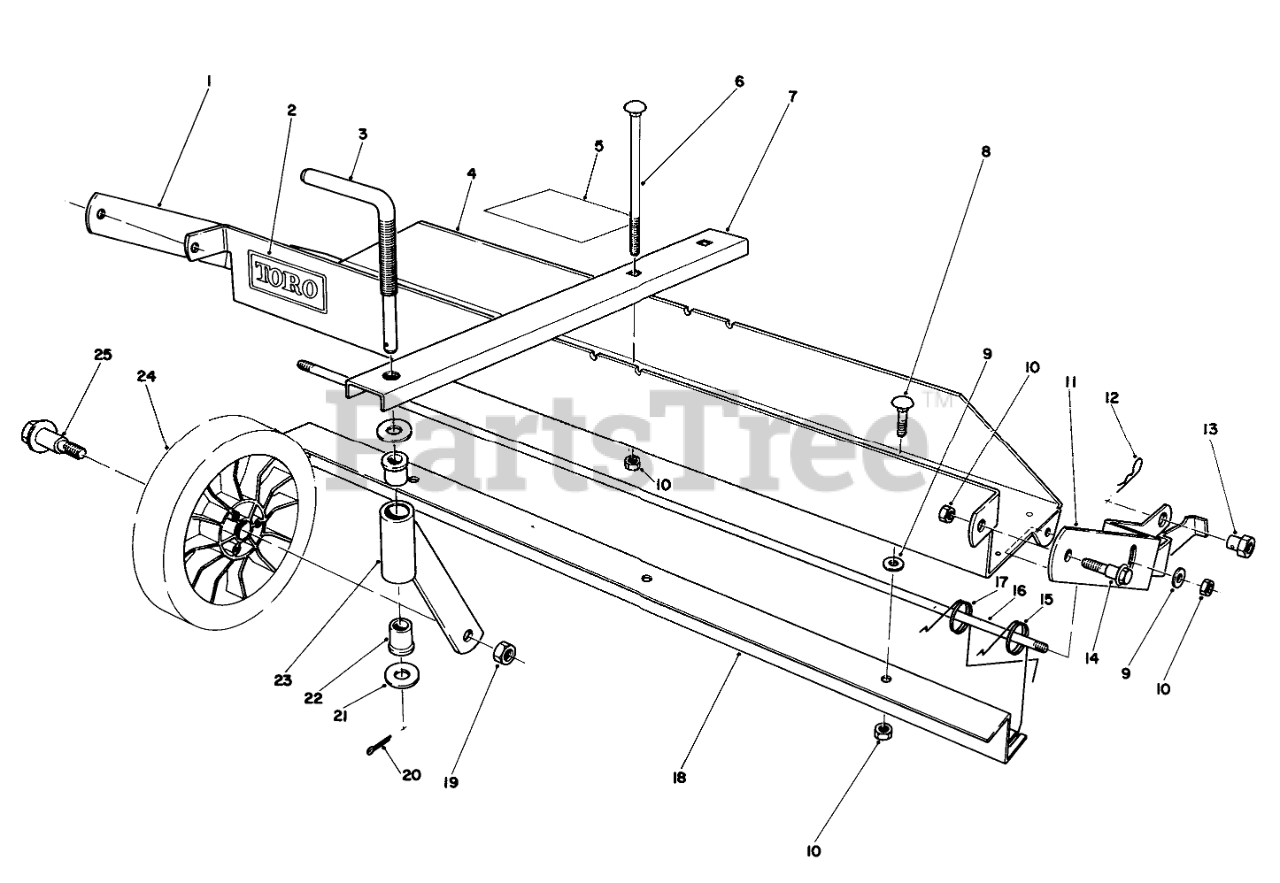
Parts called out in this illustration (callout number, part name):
1	Frame R.H.
2	Decal-Toro
3	CASTOR ADJ ROD
4	Frame-Main (Incl. Ref. #2)
5	Decal-Instruction
6	Carriage Bolt
7	Castor Frame
8	BOLT-CARR
9	WASHER-FLAT
10	NUT-HEX, SIDE DEFORM
11	LH MTG FRAME
12	PIN-COTTER, HAIR
13	PIVOT NUT
14	SCREW-SHOULDER
15	DETHATCHER SPRING
16	SPRING SUPPORT ROD
17	DETHATCHER SPRING
18	SPRING GUIDE STRAP
19	Nut
20	PIN-COTTER
21	WASHER-FLAT
22	FLANGE BUSHING
23	Castor Tube & Support
24	Wheel Assembly
25	BOLT-WHEEL
